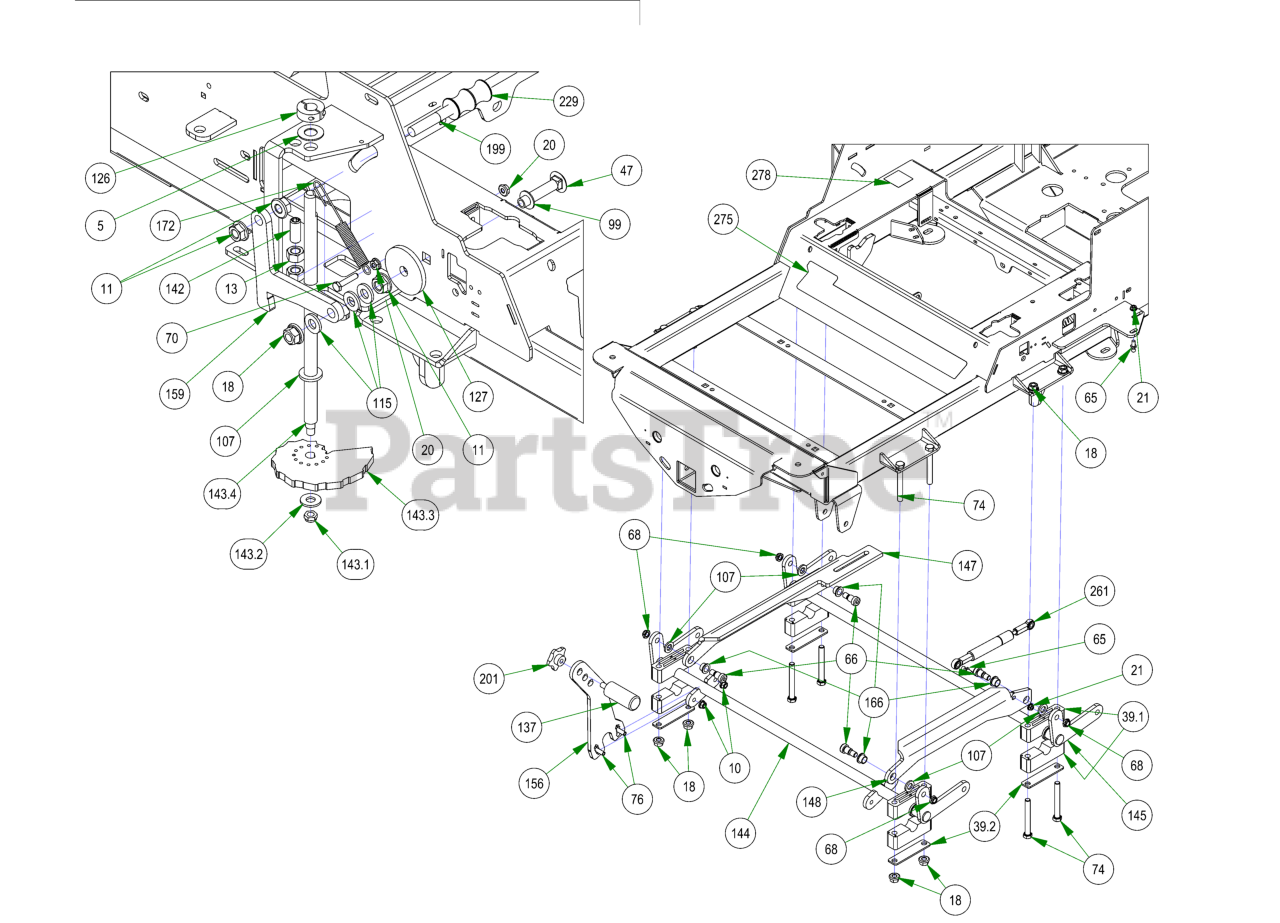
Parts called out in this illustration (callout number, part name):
5	.625 ID x 1.250 OD x .062 THK F/W Nylon
10	3/8-16 NYLON INSERT FLANGE LOCKNUT (GR.F) ZINC
11	1/2-13 HEX SERRATED FLANGE NUT HARD/ZINC
13	1/2-13 HEX NUT ZINC
18	1/2-13 NYLON INSERT FLANGE LOCKNUT ZINC
20	1/4-20 HEX SERRATED FLANGE NUT HARD/ZINC
21	5/16-18 HEX SERRATED FLANGE NUT HARD/ZINC
39	Pillow Block Assembly
39.1	Two Piece Pillow Block
39.2	Two Piece Pillow Block Strap
47	2 1/2 x 1/2 Carriage Bolt
65	10mm Damper Ball Stud-XP Linkage
66	5/8 X 5/8 SOCKET SHOULDER BOLT ZINC YELLOW
68	1/2-13 NYLON INSERT JAM LOCKNUT ZINC
70	1/4-20 X 1-1/4 HEX CAP SCREW (GR.5) ZINC
74	1/2-13 X 4 HEX CAP SCREW (GR.8) ZINC YELLOW
76	3/8-16 X 1-1/4 CARRIAGE BOLT ZINC
99	.517 SQ WDTH ID X .937 OD X .060 THICK F/W PHOS/OIL
107	.635 ID X 1.120 OD X .140 THICK FLAT WASHER NYLON
115	.505 ID X 1.000 OD X .125 THICK FLAT WASHER NYLON
126	5/8" Split Collar
127	MZ Deck Idler Spacer
137	Knurled Pedal
142	Dial Rod Plunger
143	2019 Outlaw Gen2 Deck Height Dial Rod Assy
143.1	3/8-24 Nylon Insert jam locknut
143.2	3/8" Flat Washer
143.3	2019 Deck Height Cam
143.4	2019 Outlaw Gen2 Dial Rod
144	2019 Outlaw Actuator - Front
145	2019 Outlaw Actuator - Rear
147	2019 Actuator Linkage – Right – Black
148	2019 Actuator Linkage - Left - Black
156	Foot Lift Upright Lever
159	2019 Outlaw Deck Travel Lock
166	.627 ID X .753 OD X .500 LGTH X 1.000 FLG OD X .094 FLG
172	Brake Spring
199	Seat Bracket Pin
201	Foot Pedal Knob 1/2-13
229	Travel Lock Rubber Grip
234	2022 Horizontal Diesel Frame
261	250lb Gas Spring - 61" Deck
275	2019 Renegade Cooler Cover Decal
278	2019 Deck Release Decal
